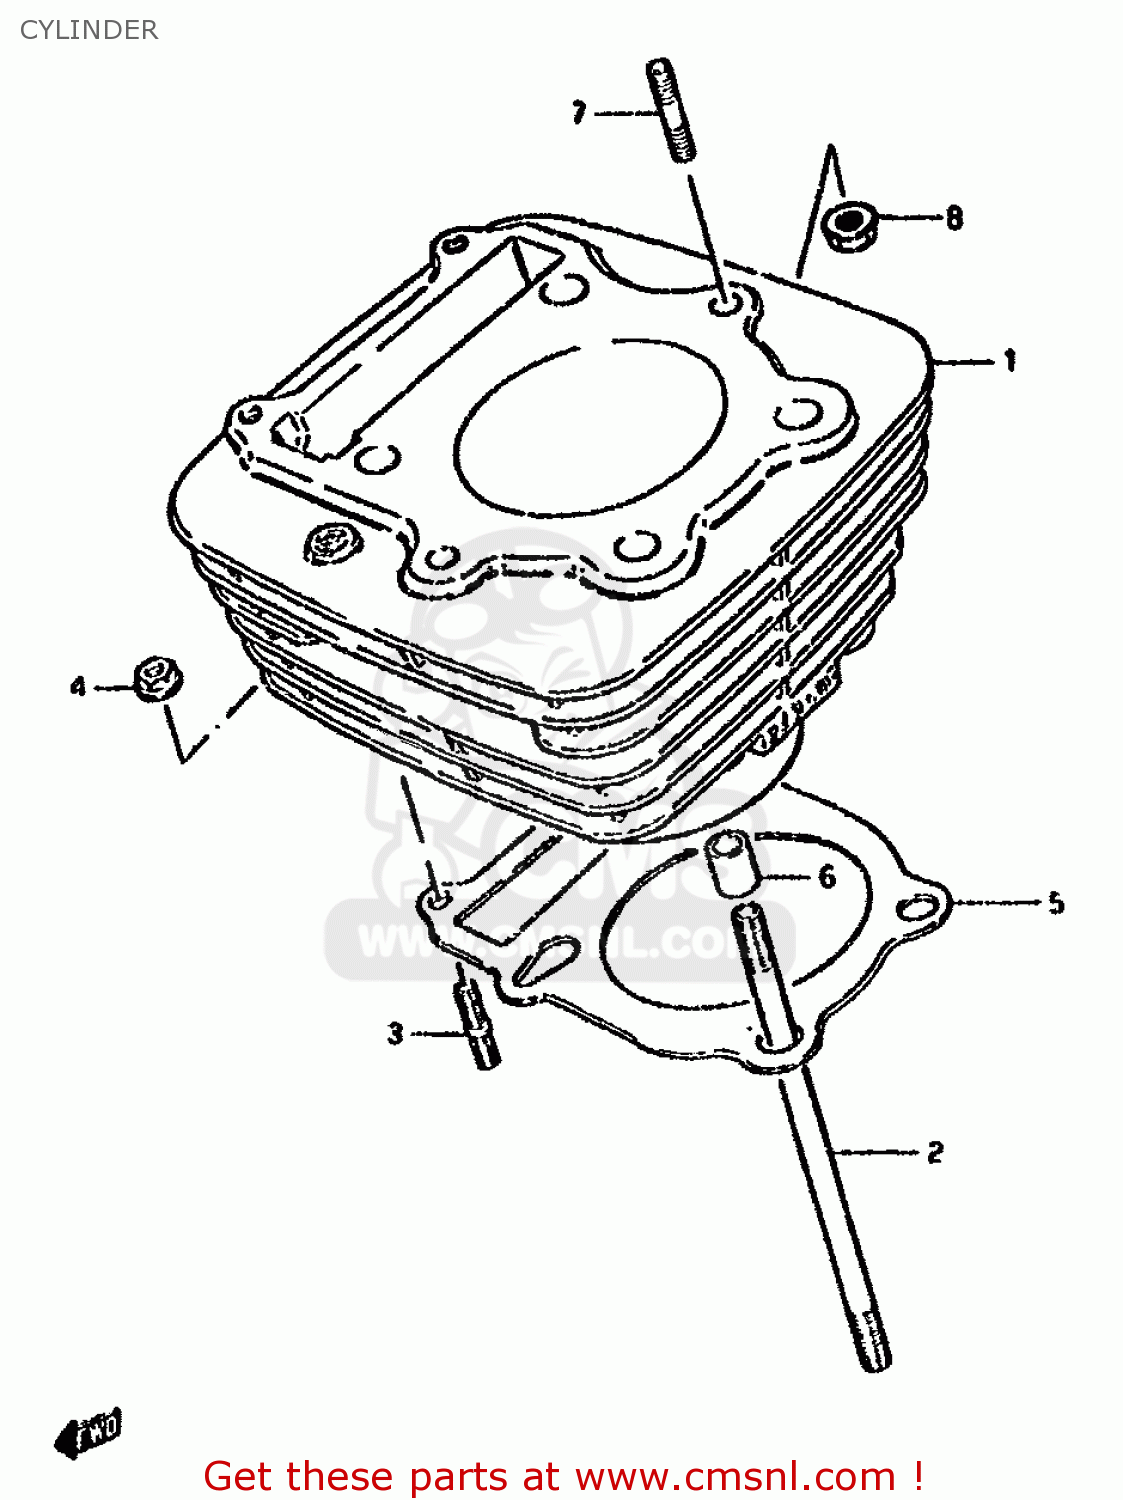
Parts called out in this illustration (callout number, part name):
1	CYLINDER
2	BOLT,STUD
3	STUD 6X25
4	NUT
5	GASKET,CYLINDER (NAS)
6	PIN
7	STUD 6X30
8	NUT
